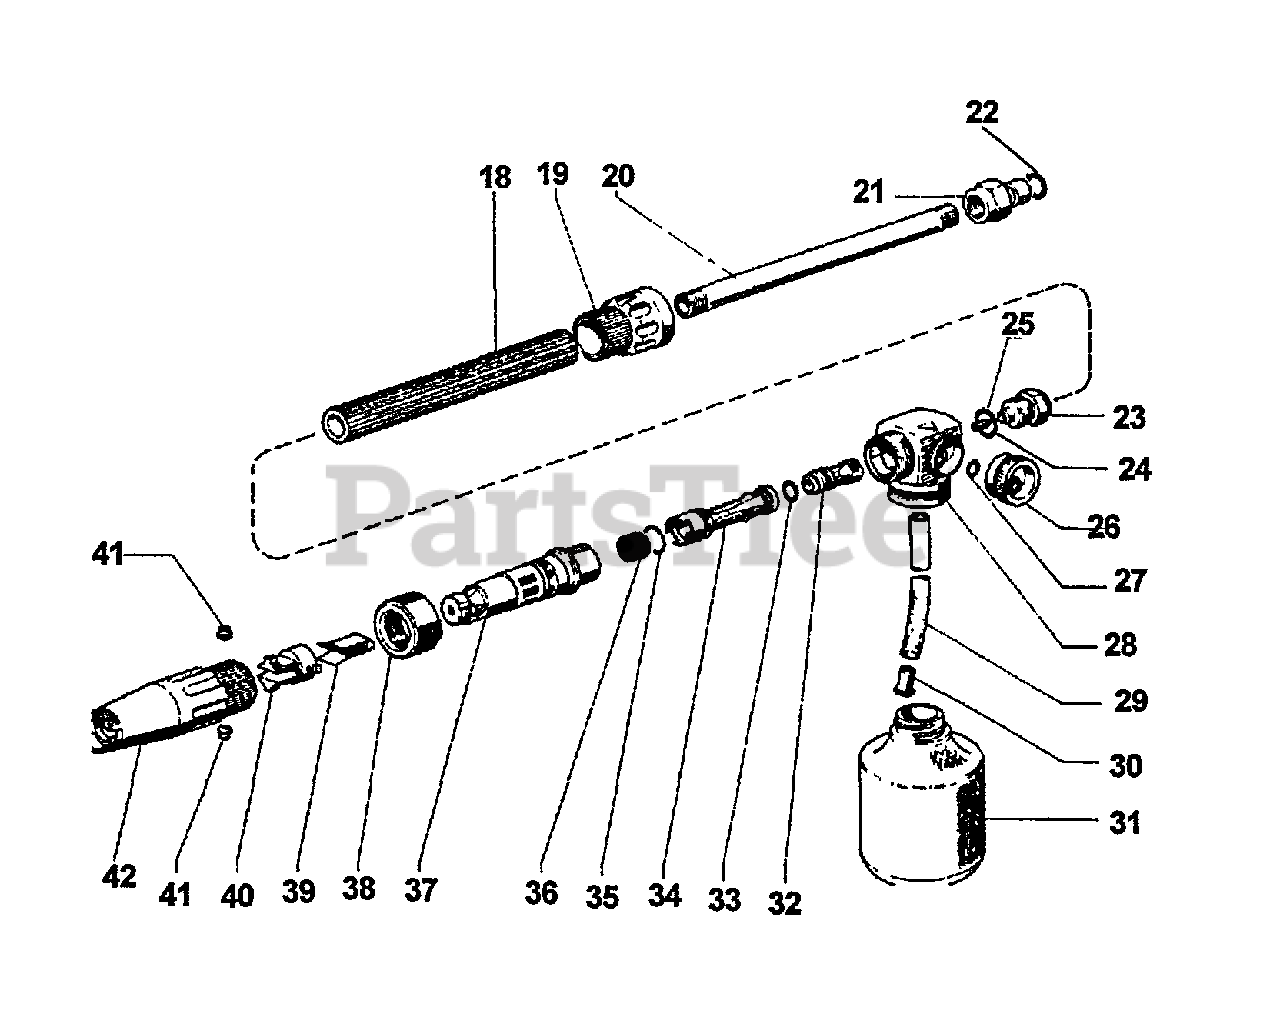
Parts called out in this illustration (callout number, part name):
18	GRIP, HANDLE
19	NUT, RING
20	PIPE
21	COUPLING, MALE
22	O-RING
23	FITTING, GREASE
24	NOZZLE - RED
25	O-RING, 0.614×0.070
26	KNOB, REGULATING
27	O-RING 0.239×.070
28	BODY
29	PIPE
30	FILTER
31	CONTAINER, 5 LITER
32	TUBE
33	O-RING
34	PIPE
35	O-RING
36	FILTER
37	CYLINDER
38	NUT
40	HOLDER, BLADE
41	CAP
42	KNOB, REGULATING
